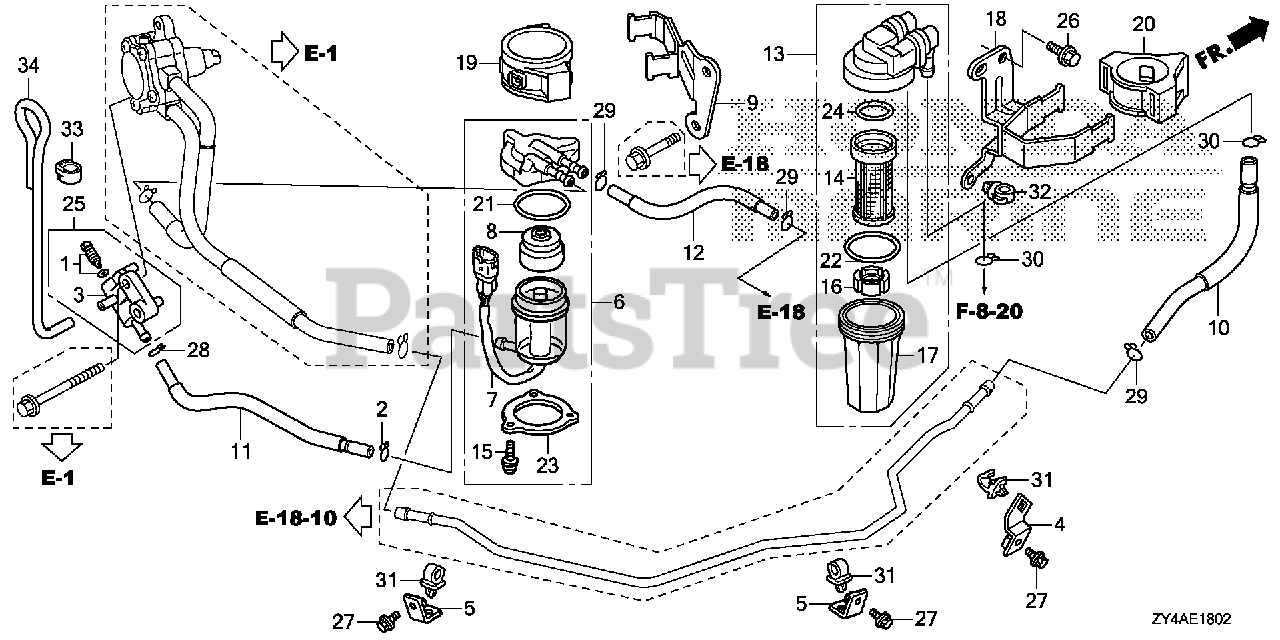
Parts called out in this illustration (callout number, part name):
1	SCREW SET, DRAIN
2	CLIP, TUBE
4	STAY, FUEL PIPE A
5	STAY, FUEL PIPE B
6	SEPARATOR ASSY., WATER
7	CUP SET, WATER SEPARATOR
8	BUFFER, PLATE
9	STAY, WATER SEPARATOR
10	TUBE B, FUEL
11	TUBE D, FUEL
12	TUBE E, FUEL
13	FILTER ASSY., FUEL
15	SCREW, PAN (5X12)
18	STAY, FUEL STRAINER
19	SUSPENSION, STRAINER
20	SUSPENSION, STRAINER
25	PETCOCK ASSY., FUEL DRAIN
26	BOLT, FLANGE (6X10)
27	BOLT, FLANGE (6X12)
28	CLIP, TUBE (B8)
29	CLIP, TUBE (B12)
30	CLIP, TUBE (B12.5)
31	CLAMP, WIRE (8MM)
32	CLIP, WIRE HARNESS (25MM)
33	CLIP, WIRE HARNESS
34	BULK HOSE, VINYL (3.5X6.5X8000) (3.5X6.5X350)
